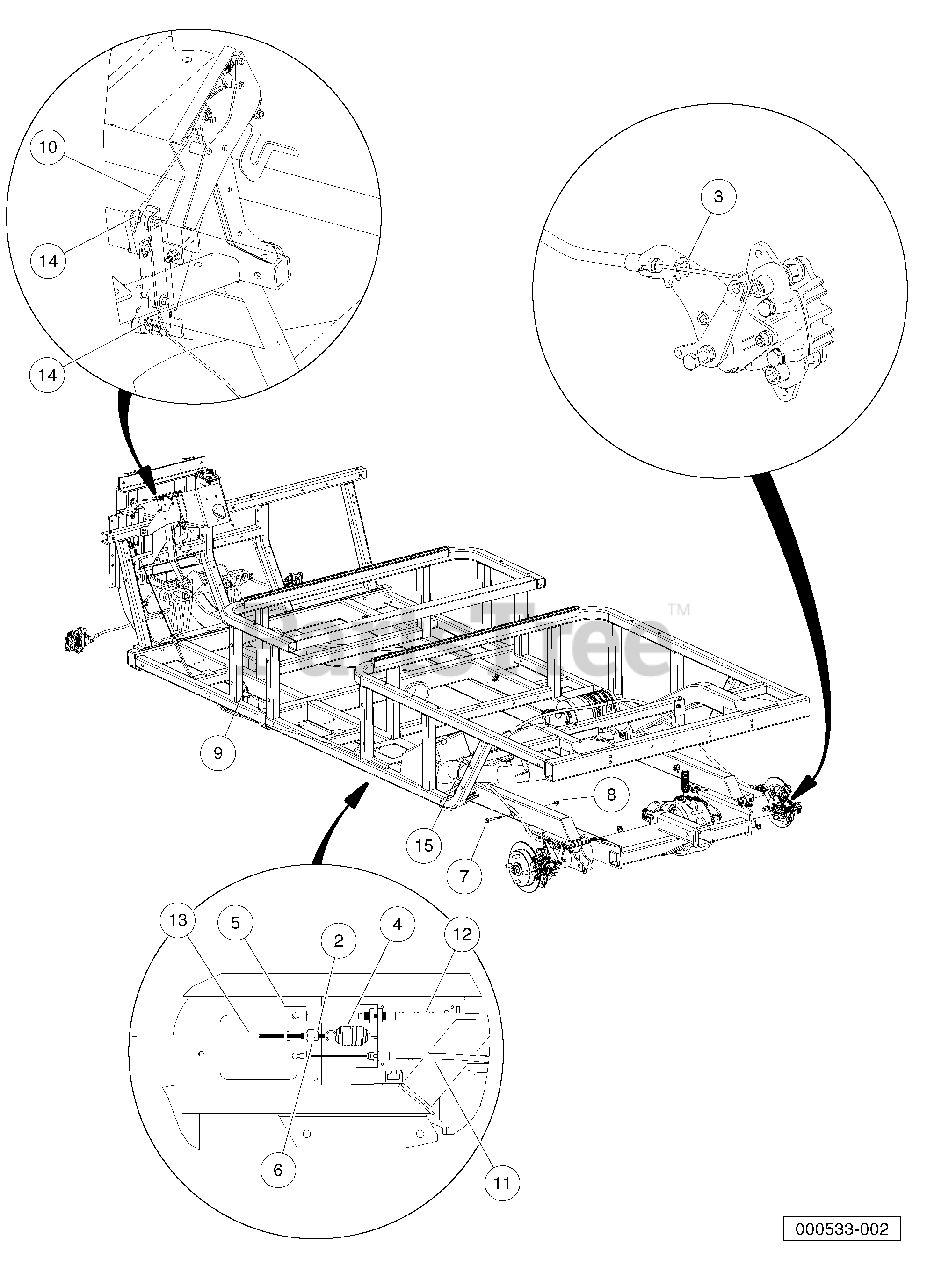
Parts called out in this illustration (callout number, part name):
1	Instl, Park, Brake, Util, 4pas
2	Nut, 5/16-24 Hex
3	E-Clip, 1/2
4	Spring, Brake Return
5	Equalizer Bracket
6	Nut, 5/16-24 Hex Cone
7	Bolt Flanged Head, M8 X 1.25 X 65
8	Lock Nut, Flg M8 X 1.25 Nylon
9	Tie Wrap, 8.00" With Mount
10	Cable, Crank, Bell, Front
11	Cable, Noncoated, Pbrake, Left
12	Cable, Noncoated, Pbrake, Rght
13	Cable, Crank, Bell, Main, Long
14	Cotter Pin, 3/32 x 1
15	Tie Wrap, 11" Nylon
